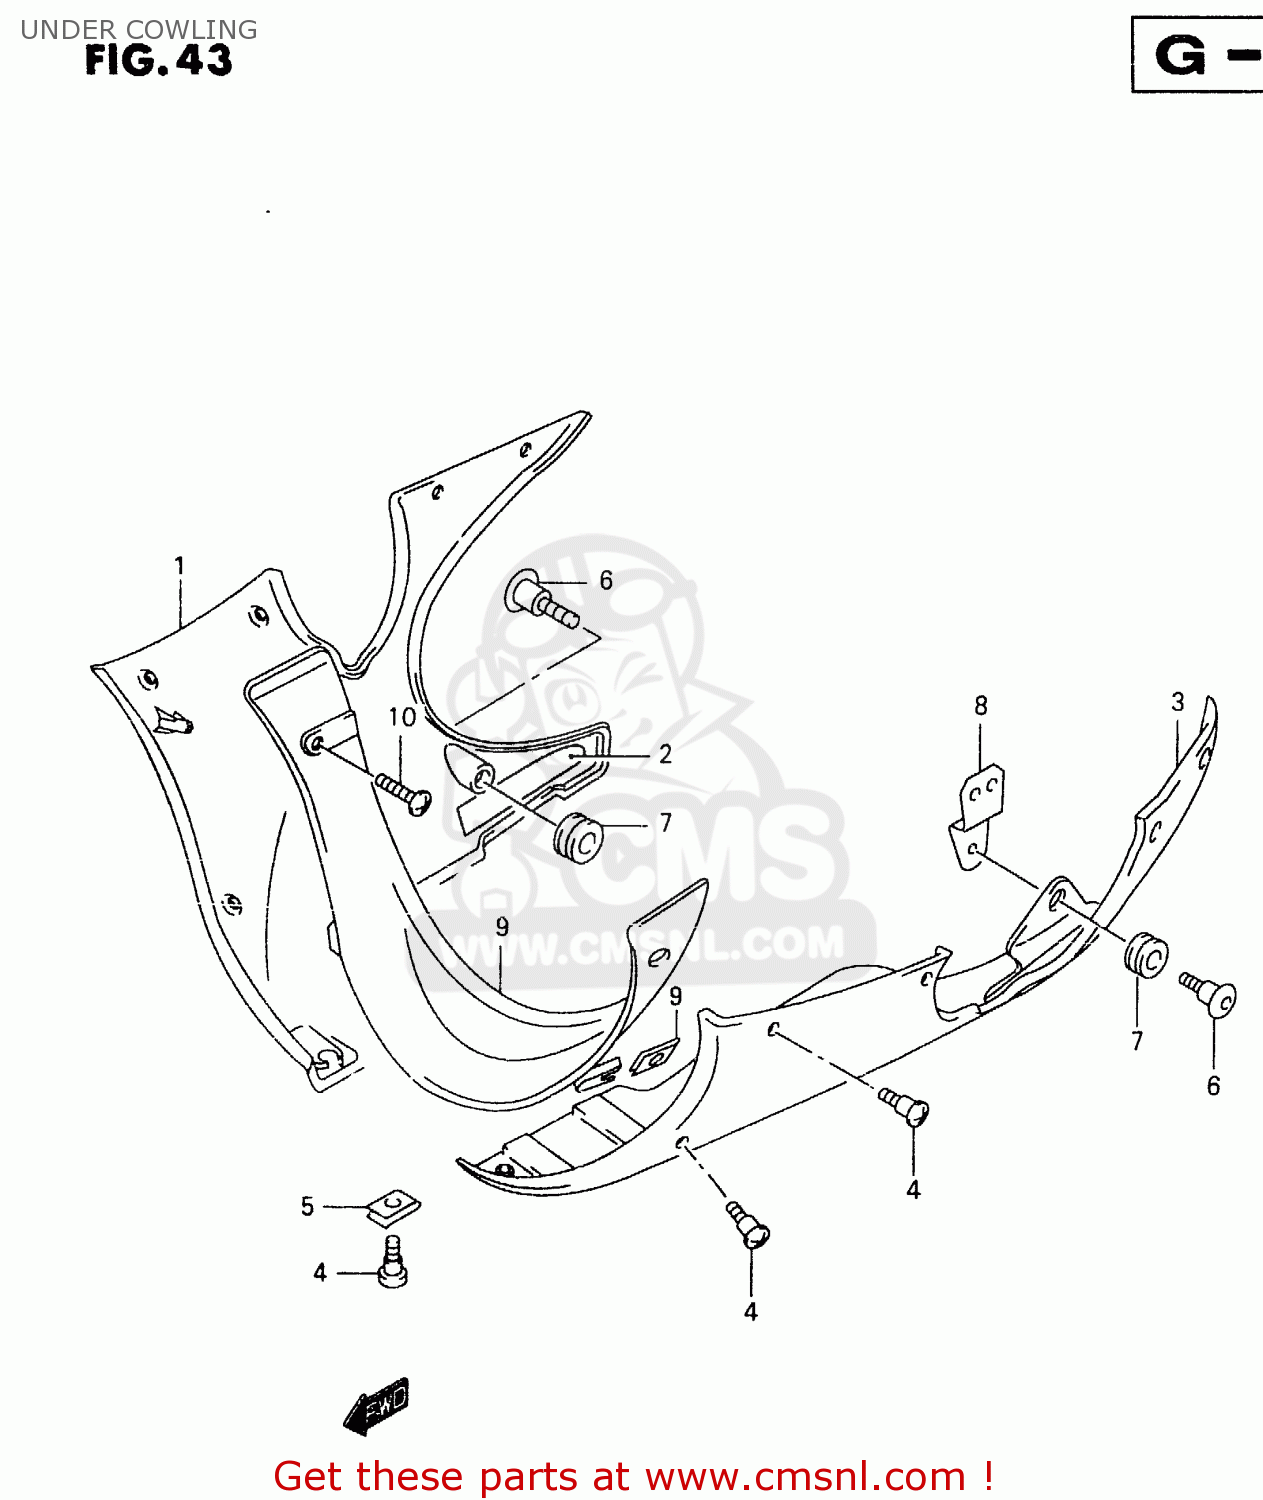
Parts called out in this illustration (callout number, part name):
1	COWLING,UNDER,R(GRAY)
2	SHIELD,COWLING UNDER,R NO.1
3	COWLING,UNDER,L
4	SCREW
5	NUT,HEADLAMP HOUSING,UPPER
6	SCREW(6X20)
7	CUSHION
8	BRACKET,UNDER COWL,L & FRAME
9	COWLING,UNDER CTR
10	SCREW
